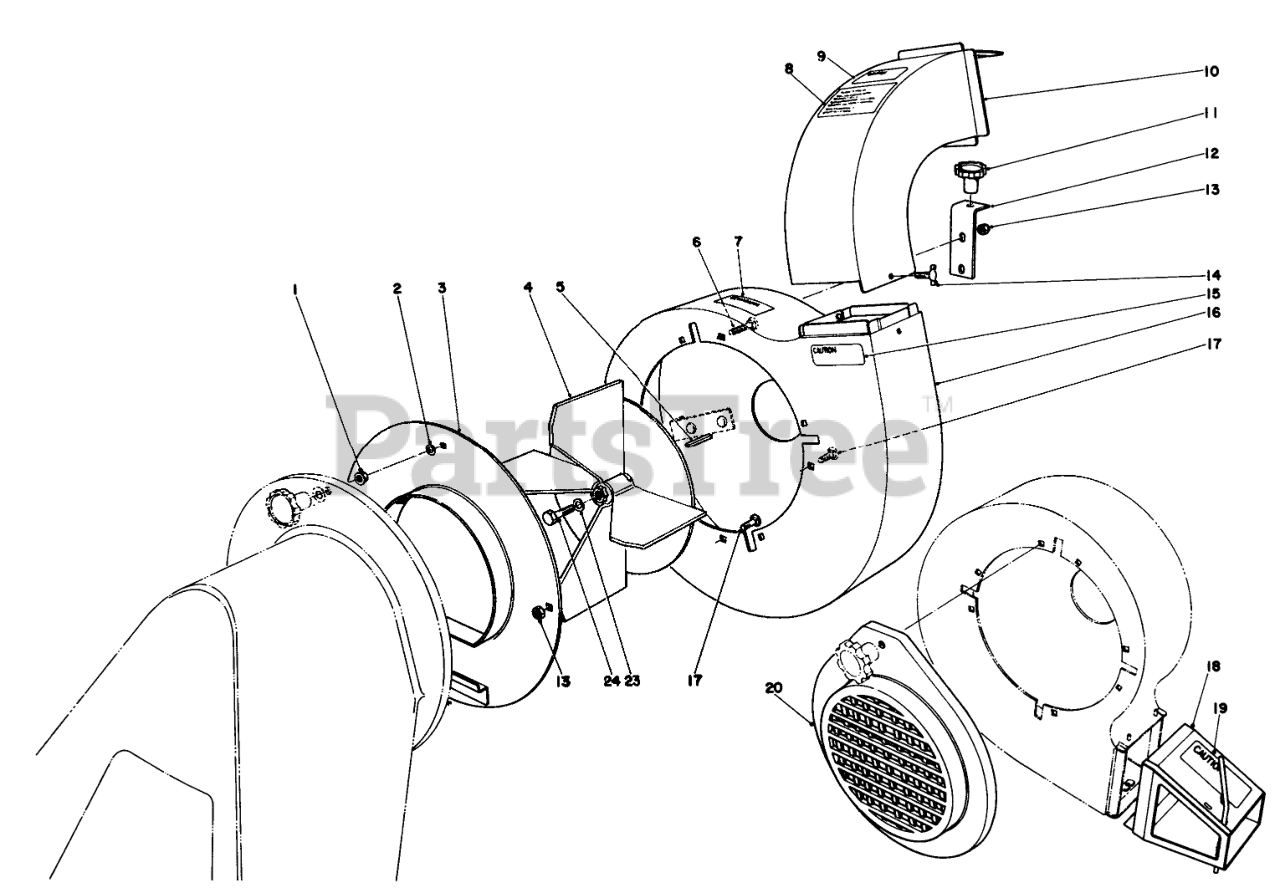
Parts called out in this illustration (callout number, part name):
1	NUT-FLANGE
2	WASHER-FLAT
3	Blower Cover
4	Fan
5	KEY-SQUARE
6	SCREW-CARR
7	ROTATE WARNING DECAL
8	TORO ADVER DECAL
9	DECAL CAUTION BAG
10	Chute-Vacuum
12	Mounting Bracket
13	NUT-LOCK, CONE
14	1/4 - 20 3/4 WING SCR
15	WARNING DECAL
16	Blower Housing
17	SCREW-CARR
18	Blower Exhaust (Incl. Ref. #19)
19	EXHAUST DECAL
20	INTAKE-BLOWER
23	Lockwasher
24	Capscrew
